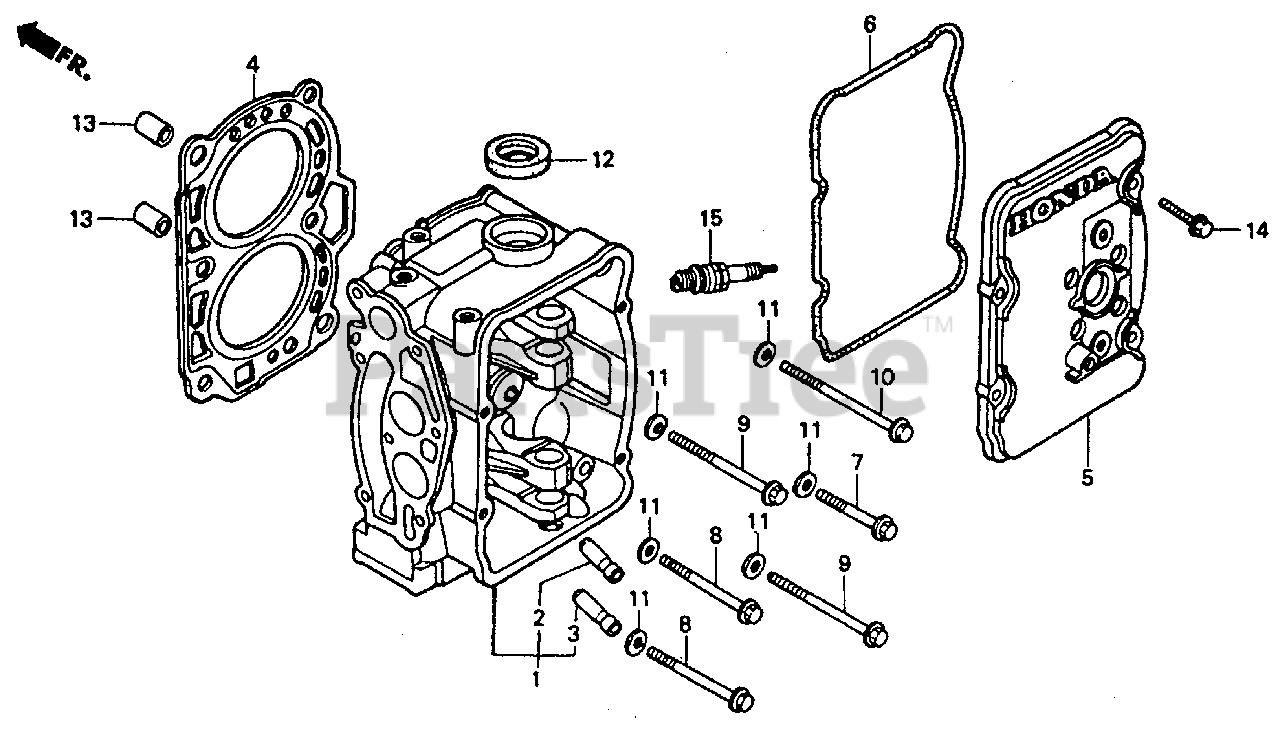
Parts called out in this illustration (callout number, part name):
1	CYLINDER HEAD *NH8* (DARK GRAY)
2	GUIDE, VALVE (OS)
3	GUIDE, EX. VALVE (OS)
4	GASKET, CYLINDER HEAD
5	COVER, CYLINDER HEAD *NH8* (DARK GRAY)
6	GASKET, HEAD COVER
7	BOLT, FLANGE (8X57)
8	BOLT, FLANGE (8X72)
9	BOLT, FLANGE (8X77)
10	BOLT, FLANGE (8X87)
11	WASHER, HEAD (8MM)
12	OIL SEAL (18X30X7)
13	PIN A, DOWEL (10X16)
14	BOLT, FLANGE (6X22)
15	SPARK PLUG (DR6HS) (NGK)
15	SPARK PLUG (X20FSR-U) (DENSO)
